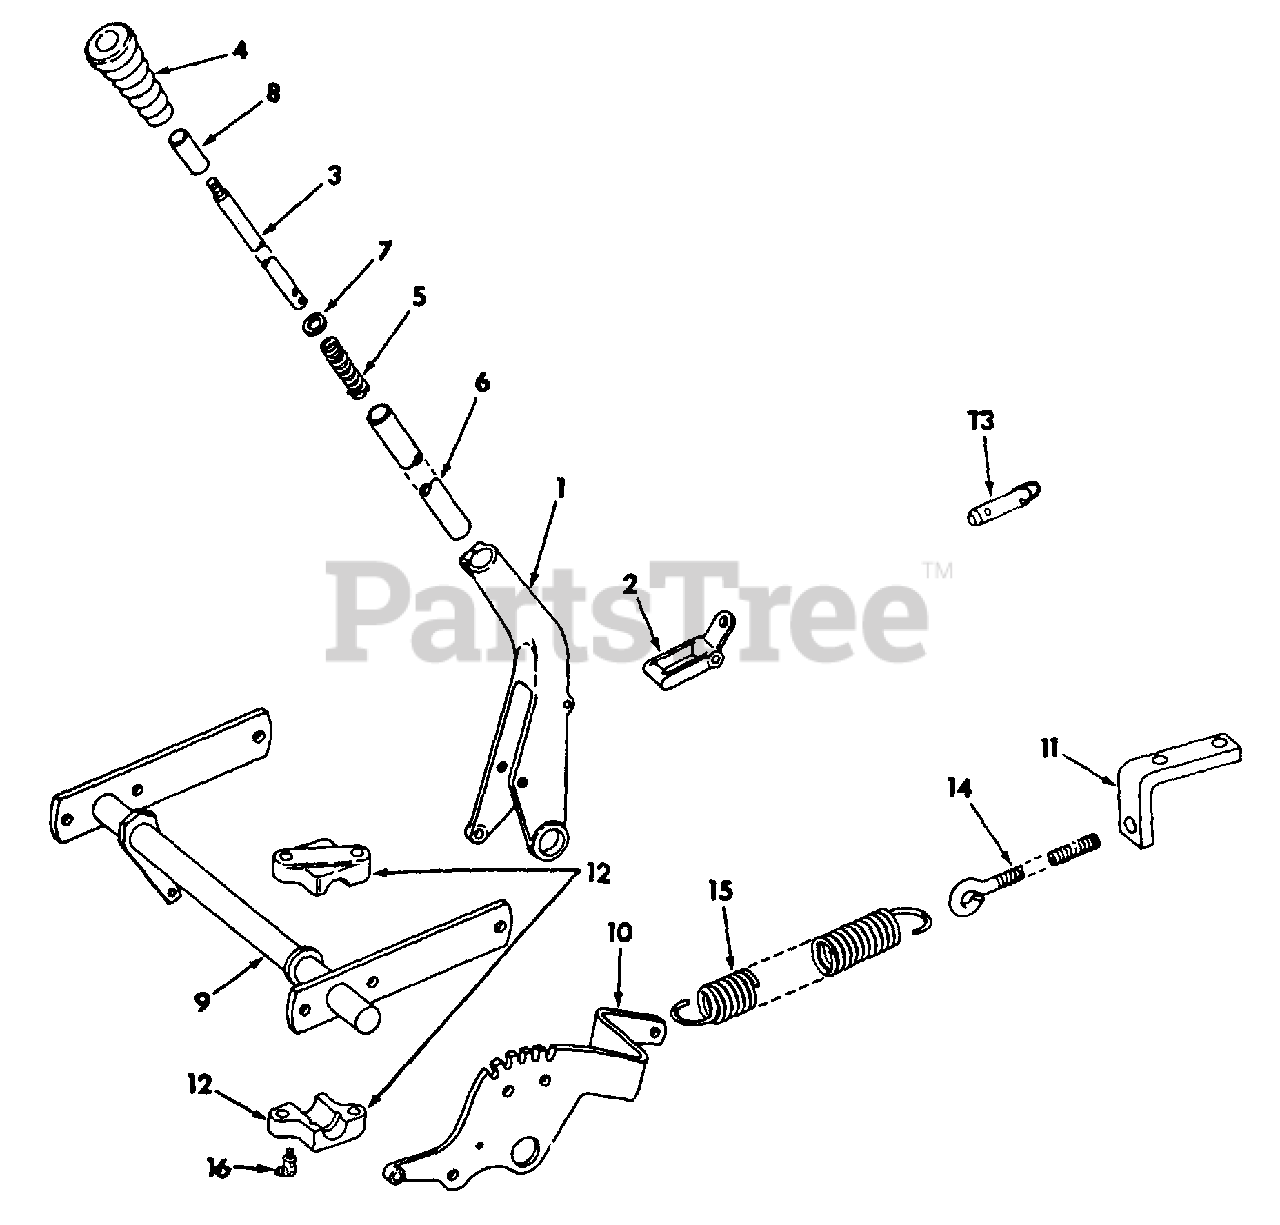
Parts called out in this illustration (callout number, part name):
1	YOKE, LIFT HANDLE
2	LEVER, LIFT HANDLE RELEASE ROD
3	ROD, LIFT HANDLE RELEASE
4	GRIP, LIFT HANDLE
5	SPRING, LIFT HANDLE RELEASE ROD
6	PIPE, LIFT HANDLE
7	RETAINER, HANDLE RELEASE ROD SPRING
8	END, LIFT HANDLE RELEASE ROD
9	ROCKSHAFT ASSY, LIFT HANDLE OPERATING
10	SECTOR ASSY, LIFT HANDLE
11	BRACKET, HELPER SPRING
12	BEARING ASSY, ROCKSHAFT
13	PIN ASSY, QUICK ATTACHABLE FAST HITCH
14	EYEBOLT, HELPER SPRING
15	SPRING, ROCKSHAFT HELPER
16	FITTING, 3/16 65 DEG ANGLE DRIVE TYPE LUB
